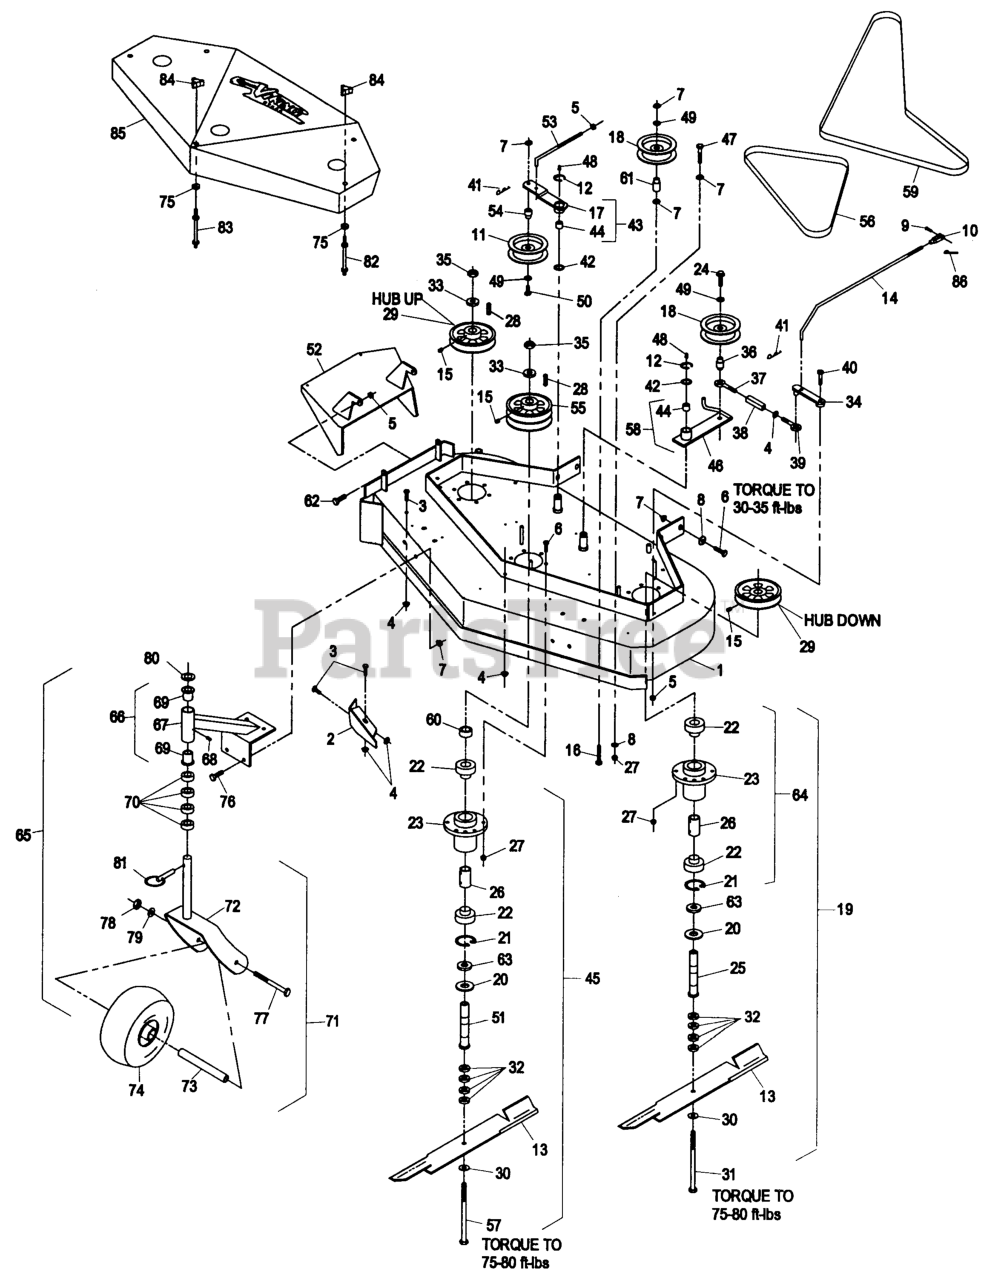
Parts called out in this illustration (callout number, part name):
2	BAFFLE-DOGLEG
9	PIN-CLEVIS
10	YOKE-ADJUSTABLE
11	IDLER,PULLEY
14	ARM-LINKAGE, ASSIST
15	SCREW-SET
16	BOLT,TAP HH3/8-16X2-1/4
17	Arm Weldmt, Rh
19	HOUSING,CUTTER COMPLETE(S
20	GUARD-BEARING, BOTTOM
22	BEARING
25	TUBE-SPINDLE, SHORT
26	SPACER-BEARING
30	WASHER-SPRING
31	SCREW-CAP, HH
33	WASHER-RETAINER, SHEAVE
36	BUSHING-ENGAGEMENT
37	EYEBOLT-THREAD, LH
38	BODY-TURNBUCKLE
39	EYEBOLT-THREAD, RH
40	BOLT,SHLDR KSKH
41	PIN-COTTER
42	WASHER-SPINDLE
43	ARM WLDMNT W/BUSHING
44	BEARING,POWDERED METAL
45	HOUSING,CUTTER COMPLETE(S
51	TUBE,SPINDLE LONG
53	LINKAGE
54	BUSHING-IDLER
56	BELT,FRONT DECK
57	SCRW,CAP HH 5/8-18X8.5
59	BELT,BLADE DRIVE 36
60	SPACER,SHEAVE/BEARING
61	BUSHING,IDLER
63	SPACER-PULLEY/BEARING
65	CASTER/MOUNT ASM
66	SUPPORT ASM
69	BEARING-FLANGED
70	SPACER-CASTER
80	WASHER-FLAT
82	STUD-SHIELD, BELT (SHORT)
83	STUD-SHIELD, BELT (LONG)
84	KNOB-3 PRONG
